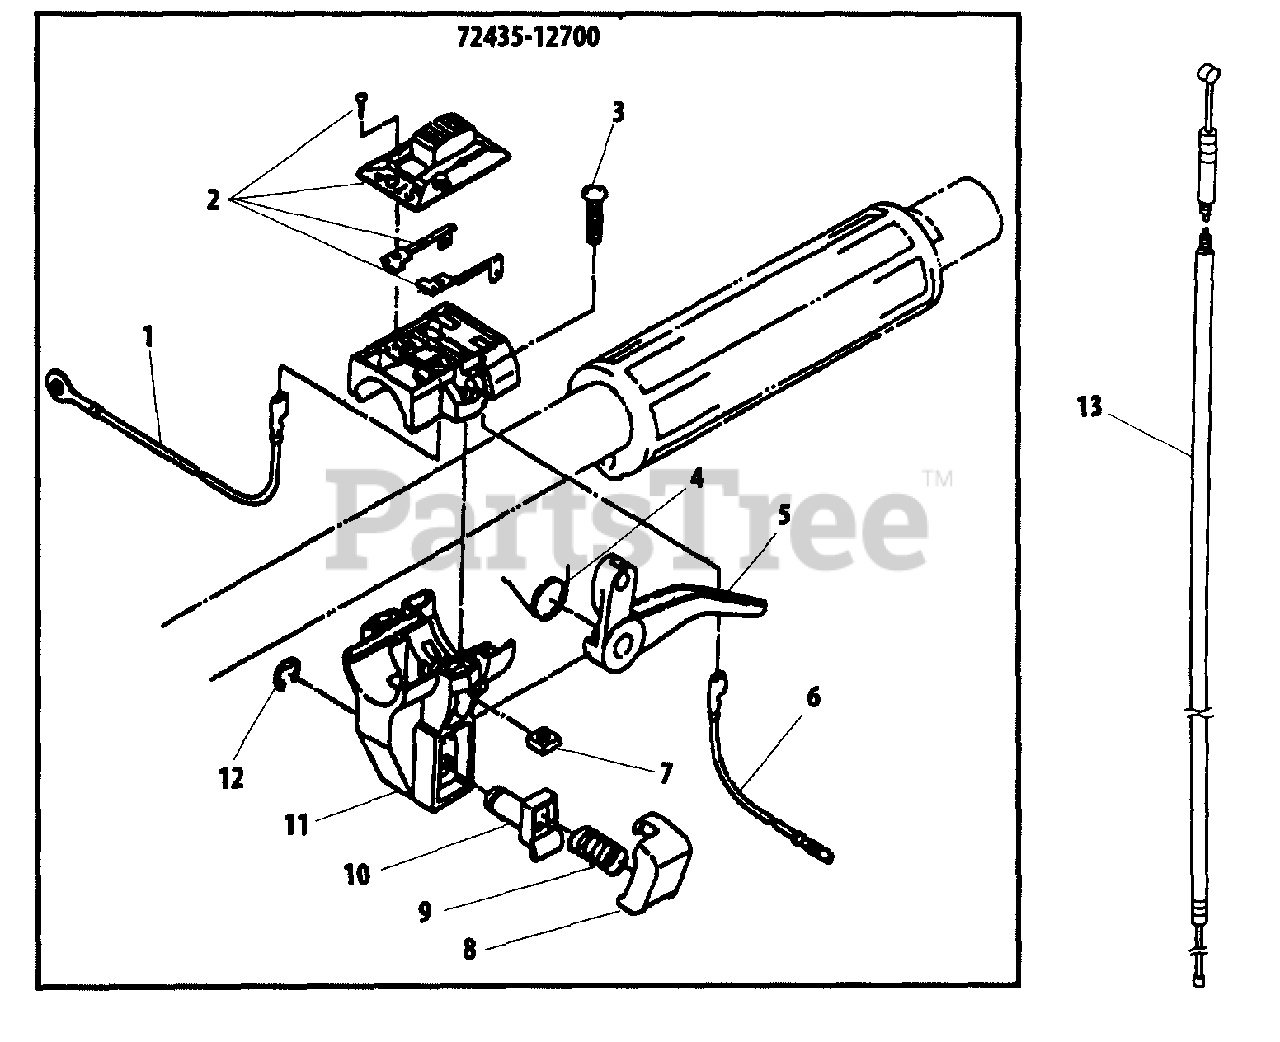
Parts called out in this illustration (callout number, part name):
1	LEAD - GROUND
2	SWITCH ASSY
3	SCREW - 5X20
4	SPRING, TRIGGER
5	LEVER, THROTTLE
6	LEAD - IGNITION
7	NUT
8	BUTTON, THROTTLE LEVER
9	SPRING
10	SHAFT
11	BODY
12	RING, RETAINING
13	CABLE, THROTTLE
